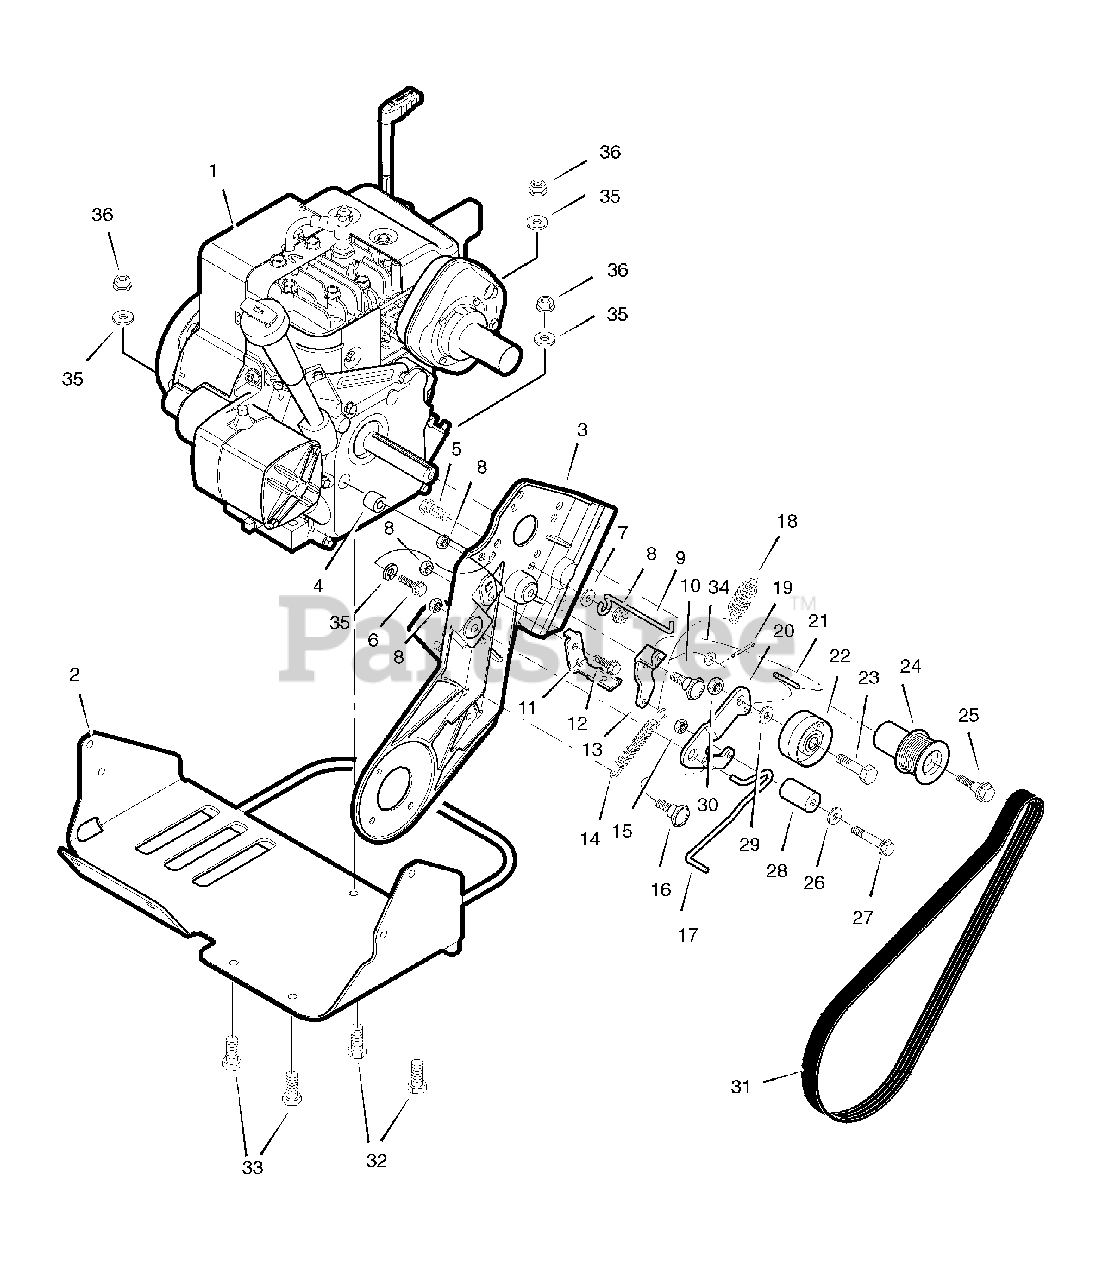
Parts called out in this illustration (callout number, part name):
1	* ENGINE, 5HP 4CY Briggs & Stratton
2	CRADLE ASSEMBLY, Engine
3	FRAME, L.H.
4	ANTIVIBRATION MOUNT, Engine
5	BOLT, Hex 5/16-18 x 0865
6	BOLT, Hex 5/16-24 x 1.125
7	WASHER, Flat
8	LOCKNUT, Hex Center 5/16-18
9	GUIDE, Belt
10	BOLT, Hex Head Shank 5/16-1/2 x 11/64
11	PAD, Brake
12	SCREW, 1/4-20 x 5/8
13	IDLER, Arm Pivot
14	SPRING, Extension .38 O.D. x .039W
15	NUT, Hex 1/4-20
16	BOLT, Hex Head Shank 5/16-1/2 x 11/64
17	WIRE, Brake
18	SPRING, Extension 3/4 O.D. X .069
19	PIN, Cotter
20	ARM, Idler
21	ROD, Clutch Linkage
22	PULLEY, Idler
23	SCREW, 3/8-16 x 1.50
24	PULLEY, Model 9 Engine
25	BOLT, Engine Pulley
26	WASHER, Flat 9/32 x 5/8 x .065
27	SCREW, 1/4-20 x 2.00
28	PINCH ROLLER
29	WASHER, Flat
30	NUT, Hex Head 3/8-16 Control Lock
31	BELT, Drive
32	BOLT, Hex 5/16-18
33	SCREW 3/8-16 x 1.00
34	WASHER, Flat
35	LOCKWASHER, Split
36	NUT, 5/16-18
